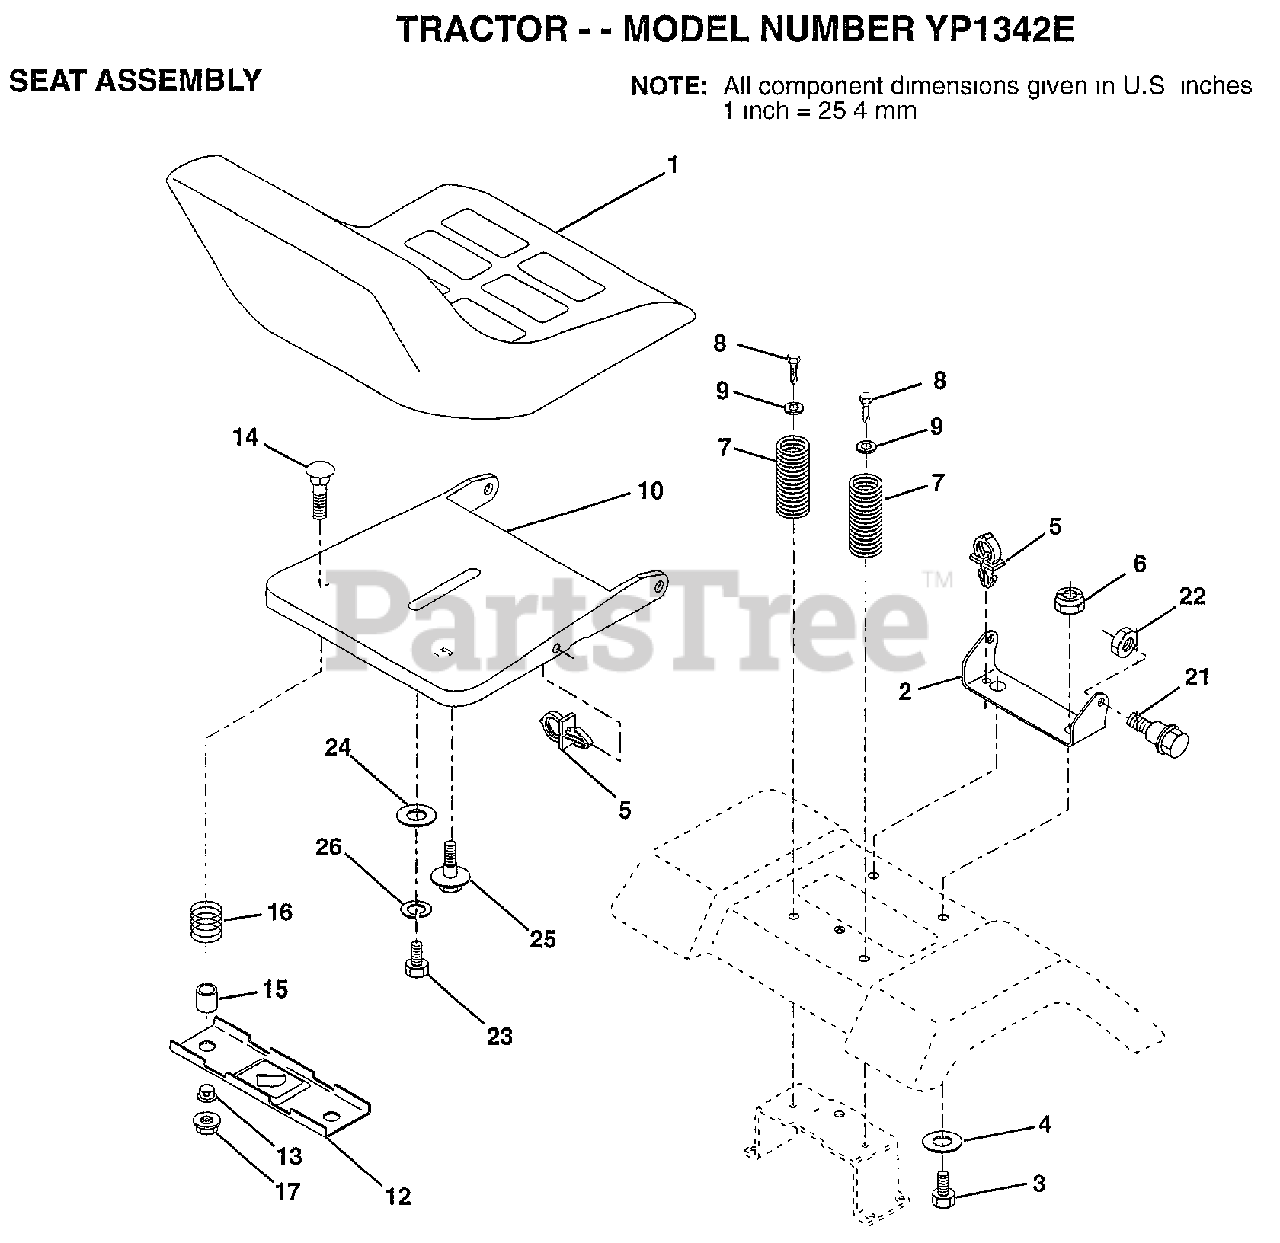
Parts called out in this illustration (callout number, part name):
1	SEAT
2	BRACKET PVT SEAT
3	BOLT
4	WASHER PM
5	CLIP.PUSH-IN.HING
6	NUT
7	SPRING COMPRESSIO
8	SCREW GTV
9	WASHER
10	PAN-SEAT
12	BRKT SWITCH
13	BUSHING
14	BOLT-RD HD SQ NK
15	SPLIT SPACER
16	SPRING
21	"BOLT,SHOULDER"
22	NUT
23	BOLT
24	WASHER
25	"BOLT,SHOULDER"
26	LOCKWASHER
